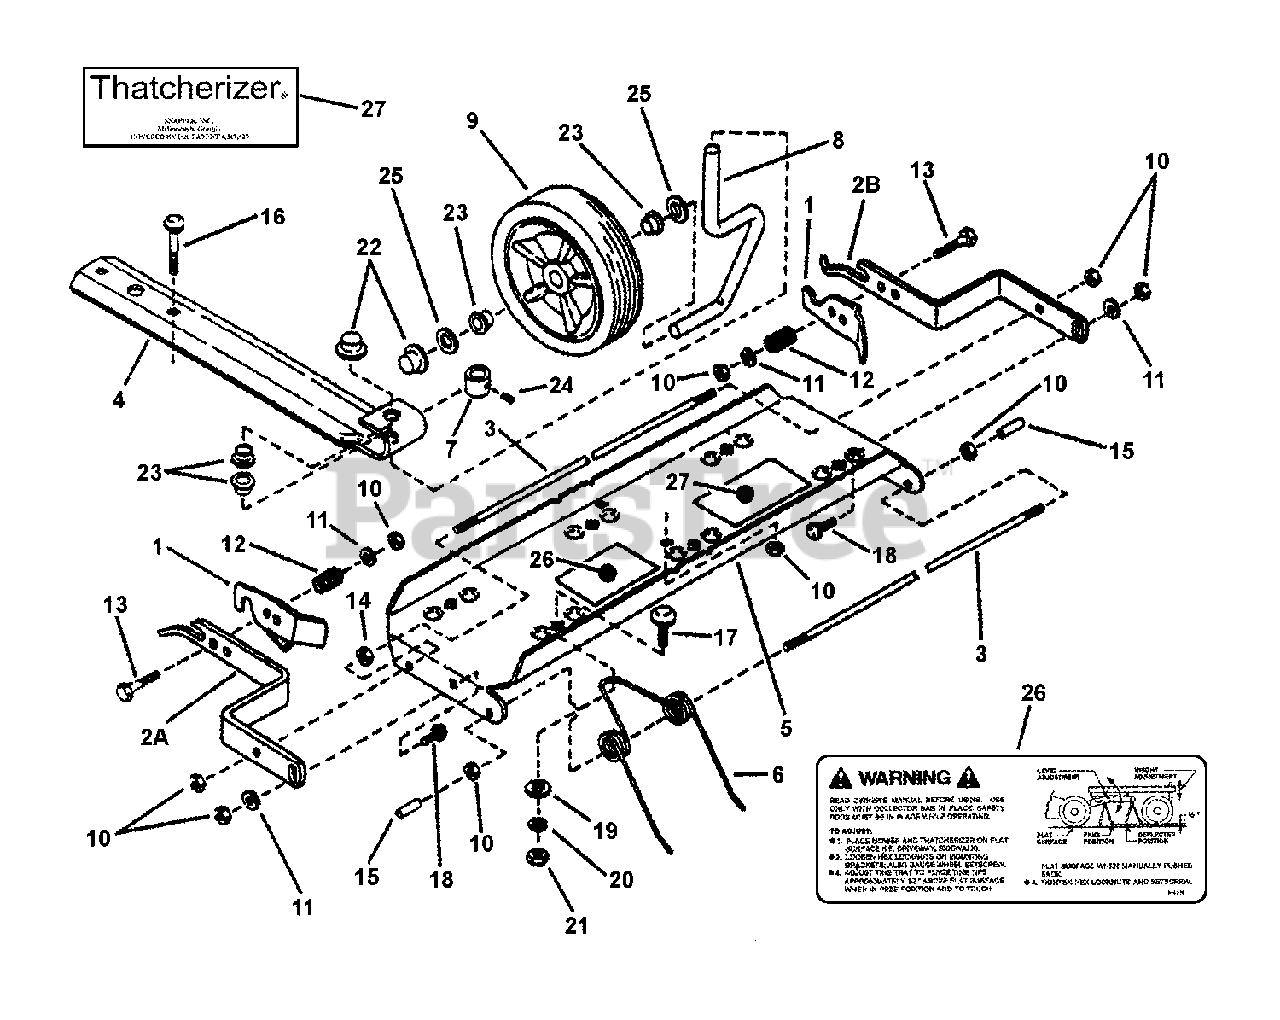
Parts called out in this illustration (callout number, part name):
1	LATCH, Frame Attachment
2A	BAR, Mount (Right Hand)
2B	BAR, Mount (Left Hand)
3	ROD, Tine
4	SUPPORT, Wheel
5	TRAY, Tine
6	SPRING, Tine Thatching
7	BUSHING, Wheel Adjuster
8	AXLE, Wheel
9	WHEEL, 7.00 x 1.50 Gage
10	NUT, 1/4-20 Hex Top Lock
11	WASHER, 1/4" Flat
12	SPRING, Compression
13	BOLT, 1/4-20 x 1-1/4" Hex, GR 5
14	NUT, 1/4-20 Hex, GR 5
15	CAP, Vinyl
16	BOLT, 1/4-20 x 2-1/2" Square Neck Carriage
17	BOLT, 5/16-18 x 1" Square Neck Carriage, GR 5
18	BOLT, 1/4-20 x 3/4" Square Neck Carriage, GR 5
19	WASHER, Reinforcing
20	WASHER, 5/16" Split Lock
21	NUT, 5/16-18 Hex, GR 5
22	NUT, 1/2" Push
23	BEARING, Nyliner
24	SET SCREW, 5/16-18 x 1/4"
25	WASHER, 1/2" Flat
26	DECAL, Adjustment
27	DECAL, Thatcherizer
